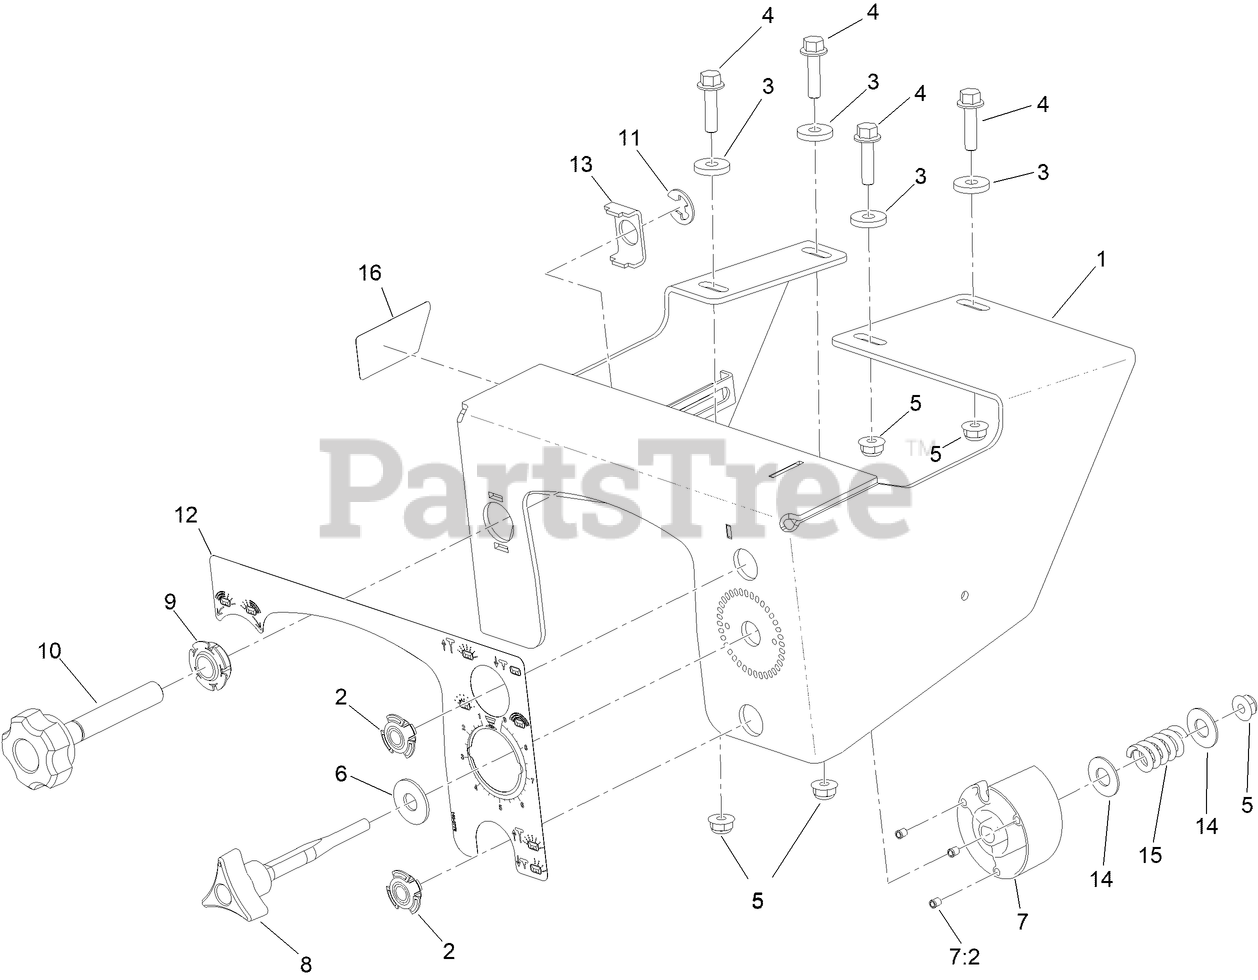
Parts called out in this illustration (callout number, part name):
1	CONSOLE-HOPPER JR36
2	BEARING-SPHERICAL
4	SCREW-HHF
5	Nut-Hex Flange
7	DIAL-RATE
7:2	PLUNGER-SPRING, BALL
8	KNOB-RATE
9	BEARING-SPHERICAL
10	KNOB-DIFFUSER
12	DECAL-CONSOLE
13	STOP-DIFFUSER
14	WASHER,FLAT,3/8ST/ST 18-8
15	SPRING-COMPRESSION
16	DECAL-PATTERN INDICATOR
